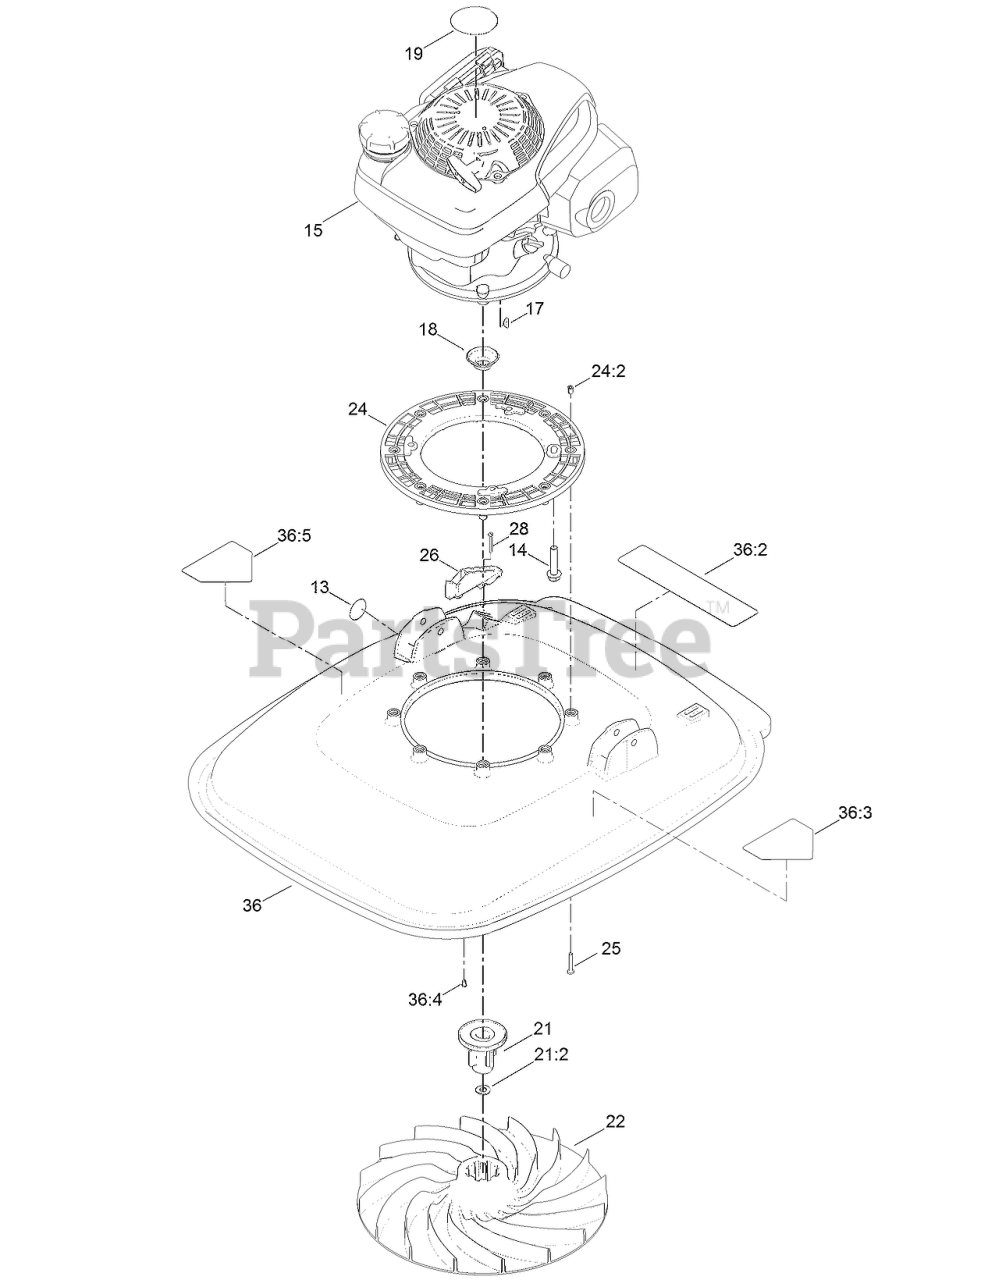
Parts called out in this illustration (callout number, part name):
13	DECAL
14	SCREW-TAPTITE
15	ENGINE-HONDA
17	KEY-WOODRUFF
18	PROTECTOR-SEAL, OIL
19	DECAL-ENGINE
21	DRIVE AND SPACER ASM
21:2	WASHER-PLAIN
22	IMPELLER
24	FRAME-ENGINE
24:2	INSERT-BRASS
25	SET-SCREW
26	BRACKET
28	SCREW
36	DECK ASM
36:2	DECAL-WARNING
36:3	DECAL-DANGER
36:4	INSERT
36:5	DECAL-DANGER
